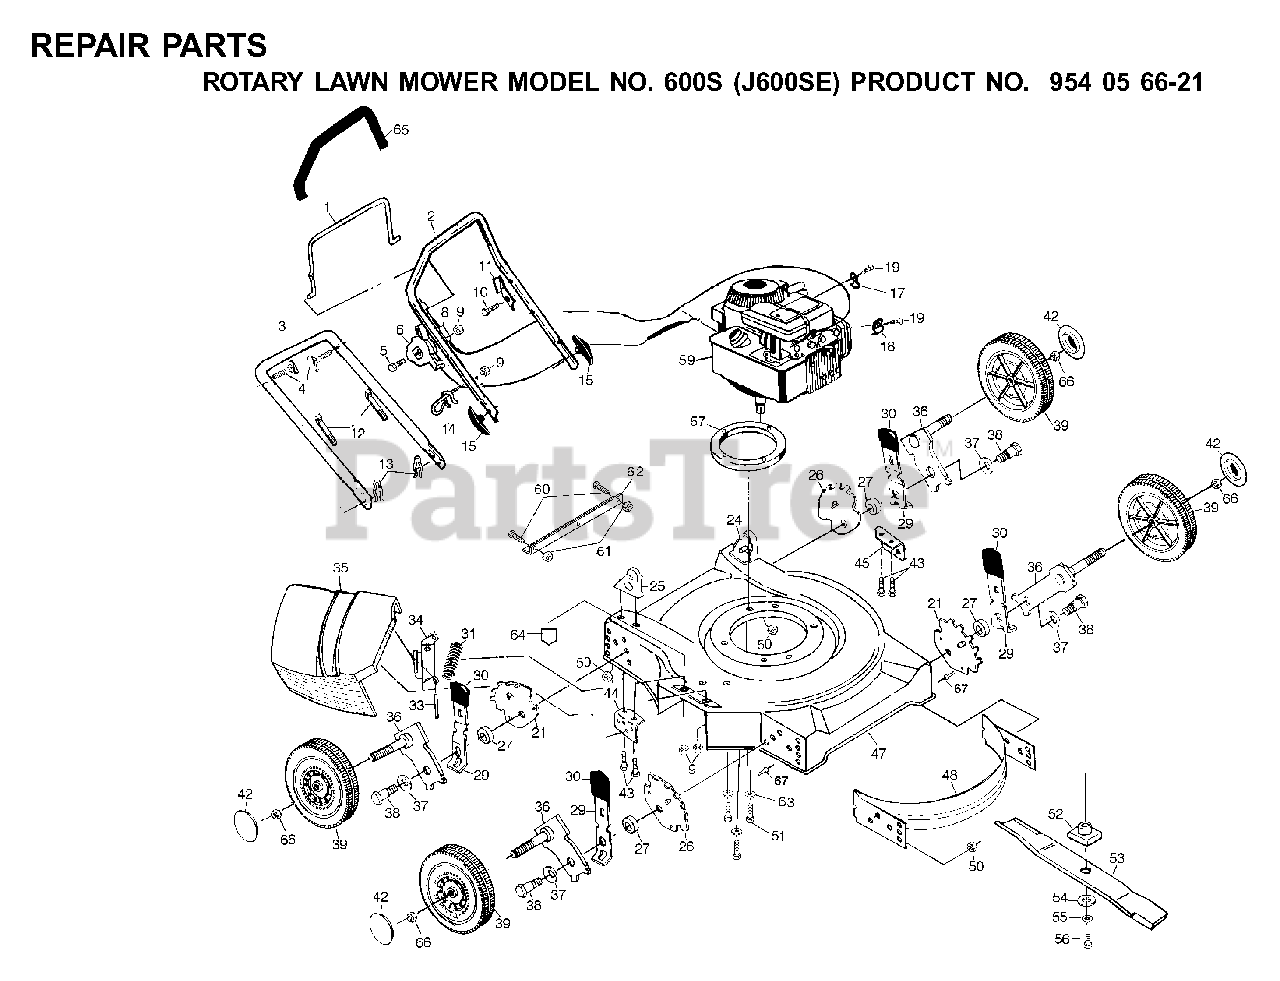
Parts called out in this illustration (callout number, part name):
1	CONTROL BAR/BLACK
4	HANDLE BOLT
6	THROTTLE CONTROL
8	ENGINE ZONE CONTROL CABLE
9	NUT
10	TAPPING SCREW
11	BRACKET UPSTOP
12	TIE GUIDE
13	HAIRPIN COTTER
15	HANDLE KNOB
17	CABLE CLAMP(ENGINE)
18	GUIDE CLIP PM
19	SCREW.HEX.HEAD.WASHER.10-16
21	BRACKET.WHL.ADJ.L
24	HANDLE BRACKET ASM. LH
25	HANDLE BRACKET ASM. RH
26	BRACKET.WHL.ADJ.R
27	RP SPACER HT ADJ
29	SELECTOR SPRING
31	SPRING PM
33	ROD.HINGE.COMBI-C
34	BRACKET PM
36	AXLE, REAR
37	BELLEVILLE WASHER
38	BOLT
43	SELF-TAPPING SCREW 5/16-18X3/4
50	LOCKNUT PM
52	BLADE ADAPTOR
53	%20"BLADE (FOR MODELS 50/51)
54	WASHER,HARDEN
55	LOCKWASHER
56	SCREW, HEX HD 3/8-24 X 1-3/8
64	DECAL MOWER CUT/FINGER
65	GRIP.HANDLE.FOAM
66	HEX FLANGE LOCKNT
67	RIVET BLIND
